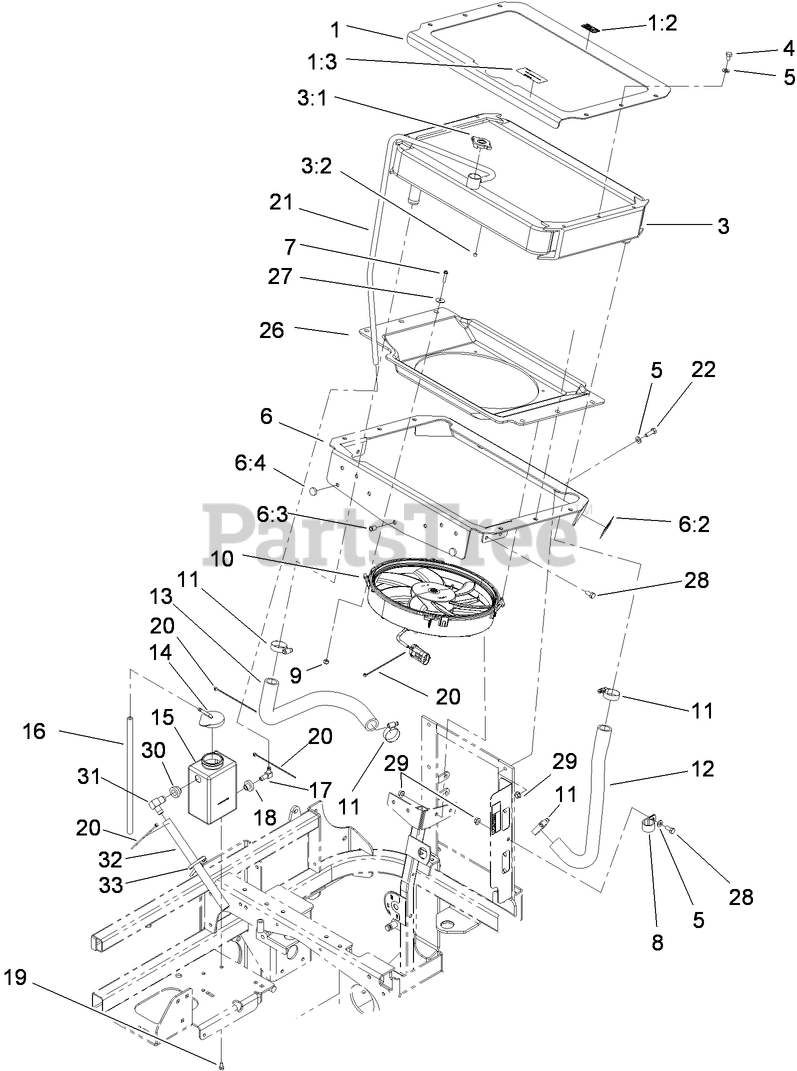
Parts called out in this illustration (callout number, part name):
1	TOP RADIATOR PLATE ASM
1:2	DECAL-SURFACE, HOT
1:3	DECAL-ANTIFREEZE
3	RADIATOR ASM
3:1	CAP-RADIATOR
3:2	PLUG-PIPE
4	SCREW-HH
5	WASHER-PLAIN
6	BOTTOM RAD PLATE ASM
6:2	DECAL-FAN, RADIATOR
6:3	INSERT-NUT
6:4	BUMPER
8	CLIP-LOOM
9	NUT-LOCK, HH
10	FAN-HI PERFORMANCE
11	CLAMP-HOSE
12	HOSE-RADIATOR, LH
13	HOSE-RADIATOR, RH
14	CAP-TANK, OVERFLOW
15	TANK-OVERFLOW
16	HOSE-LINE, FUEL
17	FITTING-ELBOW
18	BUSHING-VALVE, FUEL
19	SCREW-HH
20	TIE-CABLE
21	HOSE-OVERFLOW
22	SCREW-HH
26	SHROUD
27	WASHER
28	SCREW-HH
29	NUT-HF
30	BUSHING
31	FITTING-ELBOW
32	HOSE-OVERFLOW
33	TIE-PLASTIC
